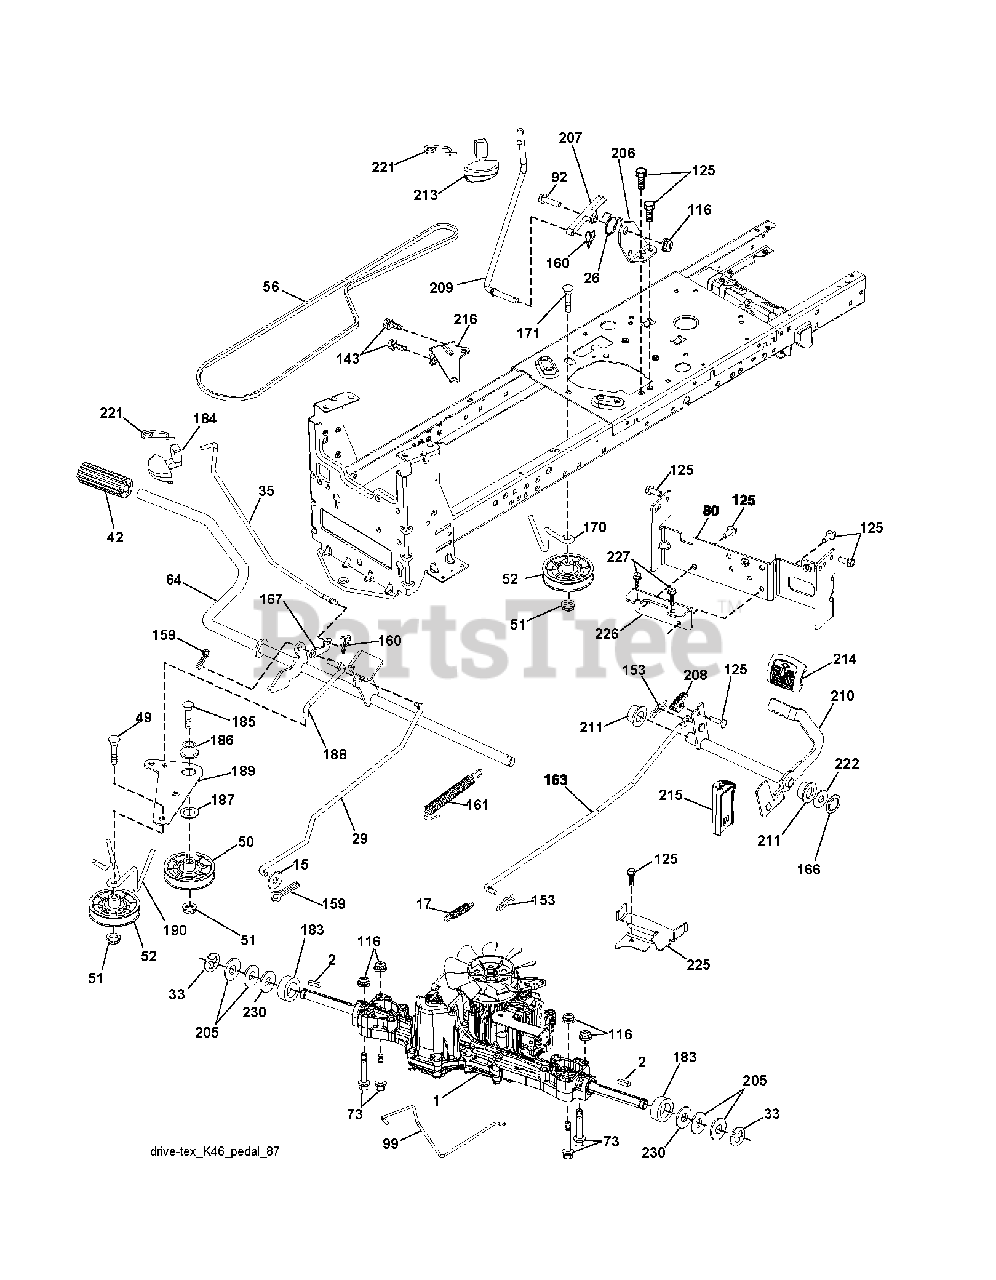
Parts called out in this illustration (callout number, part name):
2	SQUARE KEY
15	WASHER
17	SPRING.BRAKE.K46.GREEN
26	SPRING.RETURN.CRUISE
29	ROD.BRAKE.K46
35	ROD.BRAKE.PARTK.HUSQ.TEX
42	PEDAL COVER T
50	IDLER.FLAT.910.OFFSET
51	NUT LOCK FLG 3/8-16 UNC
52	IDLER.V-GROOVE.910.OFFSET
56	V-BELT.MOWER.92.40.42/K46
64	SHAFT.ASM.PEDAL.BRK.CNTR
80	STRAP.TORQUE.K46.K57R.TT
92	BOLT
99	ROD.SPRING.BYPASS.K46.LT.Z
116	NUT LOCK HEX FLANGE 5/16-18
125	SCREW
143	SCREW LT
153	RETAINER M
159	COTTER PIN
160	RETAINER CLIP
161	SPRING, RETURN LT
163	ROD.CONTROL.K57R.K46
166	NUT.PUSH.625
167	LATCH.BRAKE.SPRING
170	KEEPER.V-IDLER.CENTER.
183	SPACER AXLE
184	RB HANDLE.PARKG.BRK.HUS/PRED
186	SPACER.RETAINER
187	WASHER 12/32X2X10GA
188	RP LINK.CLUTCH.GROUND.DRIVE
189	BELLCRANK.GROUND.DRIVE.TEX.
190	KEEPER.BELLCRANK.DRIVE
206	BRKT.MOUNT.LATCH.CRUIS
207	LATCH.CONTROL.CRUISE
208	GEAR.SECTOR.CONTROL.CR
209	ROD.CONTROL.CRUISE.GT.
210	ROCKER.ASM.PEDAL.CONTR
211	BEARING.NYLON
213	KNOB.CONTROL.CRUSIE.HU
214	PEDAL.FORWARD.PAD.TEX
215	PEDAL.REVERSE.TEX.GT.4
216	BRACKET.PULLEY.IDLER.W/TEX
221	RETAINER.SPRING.CLIP.H
222	WASHER 21/32 X 1-1/4 X 10 GA.
225	KEEPER.BELT.TRANSAXLE.K46
226	BRACKET.MOUNT.TORQUE.K46.TLT
227	SCREW
230	WASHER.HARDENED
